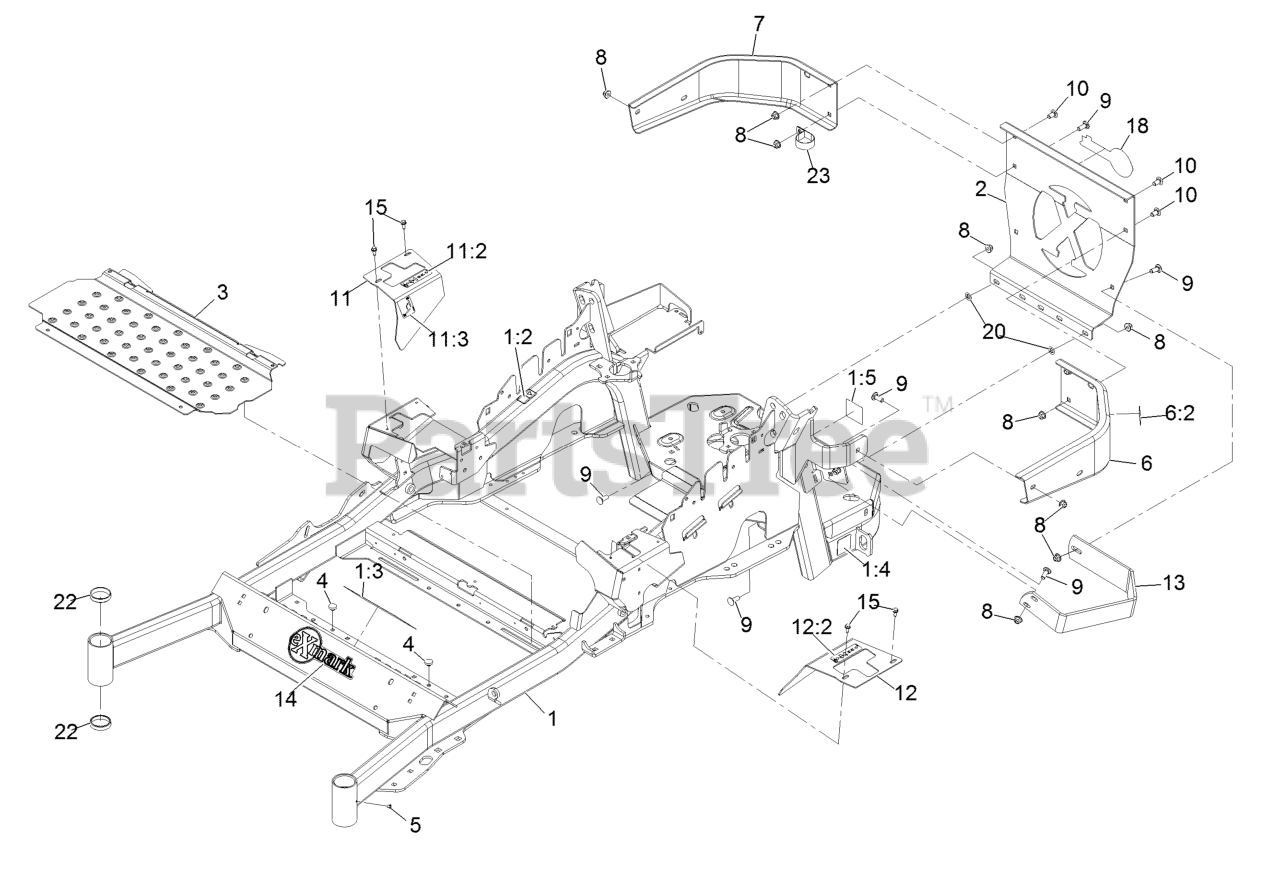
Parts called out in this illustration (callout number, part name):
1	Mainframe ASM
1:2	Decal-Warning
1:3	Decal-Danger
1:4	Decal-Hazard, Pinched Finger
1:5	Decal-Spark Arrester
2	Plate,Rear Guard
6	LH Bumper ASM
6:2	Decal-Warning
7	Bumper-RH
8	Nut-Nyloc 3/8-16 Flg
9	Bolt-Carriage 3/8-16 X 1
10	Bolt-Carriage 3/8-16 X 3/4
11	RH Motion Control Cover ASM
11:2	Decal-Control, Motion
11:3	Decal-Park Brake, CE
12	LH Motion Control Cover ASM
12:2	Decal-Control, Motion
13	Guard-Muffler
14	Decal-Exmark
15	Screw-HWH 1/4-20 X .62
18	Decal-Exmark Logo
20	Nut-Push 3/8-16
22	Cup-Bearing Tapered Roller
